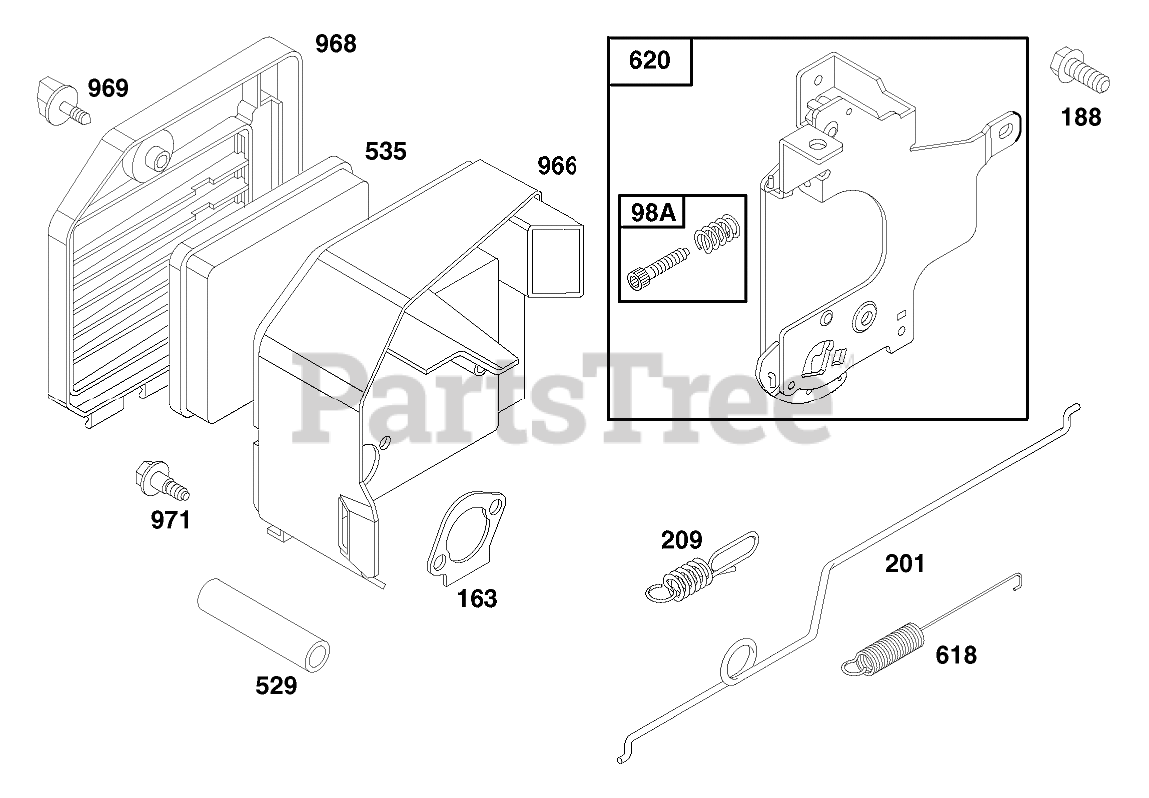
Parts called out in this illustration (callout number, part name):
37	GUARD - FLYWHEEL
98A	SPEED ADJUST. SCREW ASM
163	AIR CLEANER GASKET
188	Screw-Cap
201	GOVERNOR LINK
209	GOVERNOR SPRING
529	TUBE - BREATHER
535	FILTER ELEMENT
618	RETURN SPRING
620	CARBURETOR BRACKET
966	AIR CLEANER BASE
968	AIR CLEANER COVER
969	AIR CLEANER SCREW
971	AIR CLEANER SCREW
